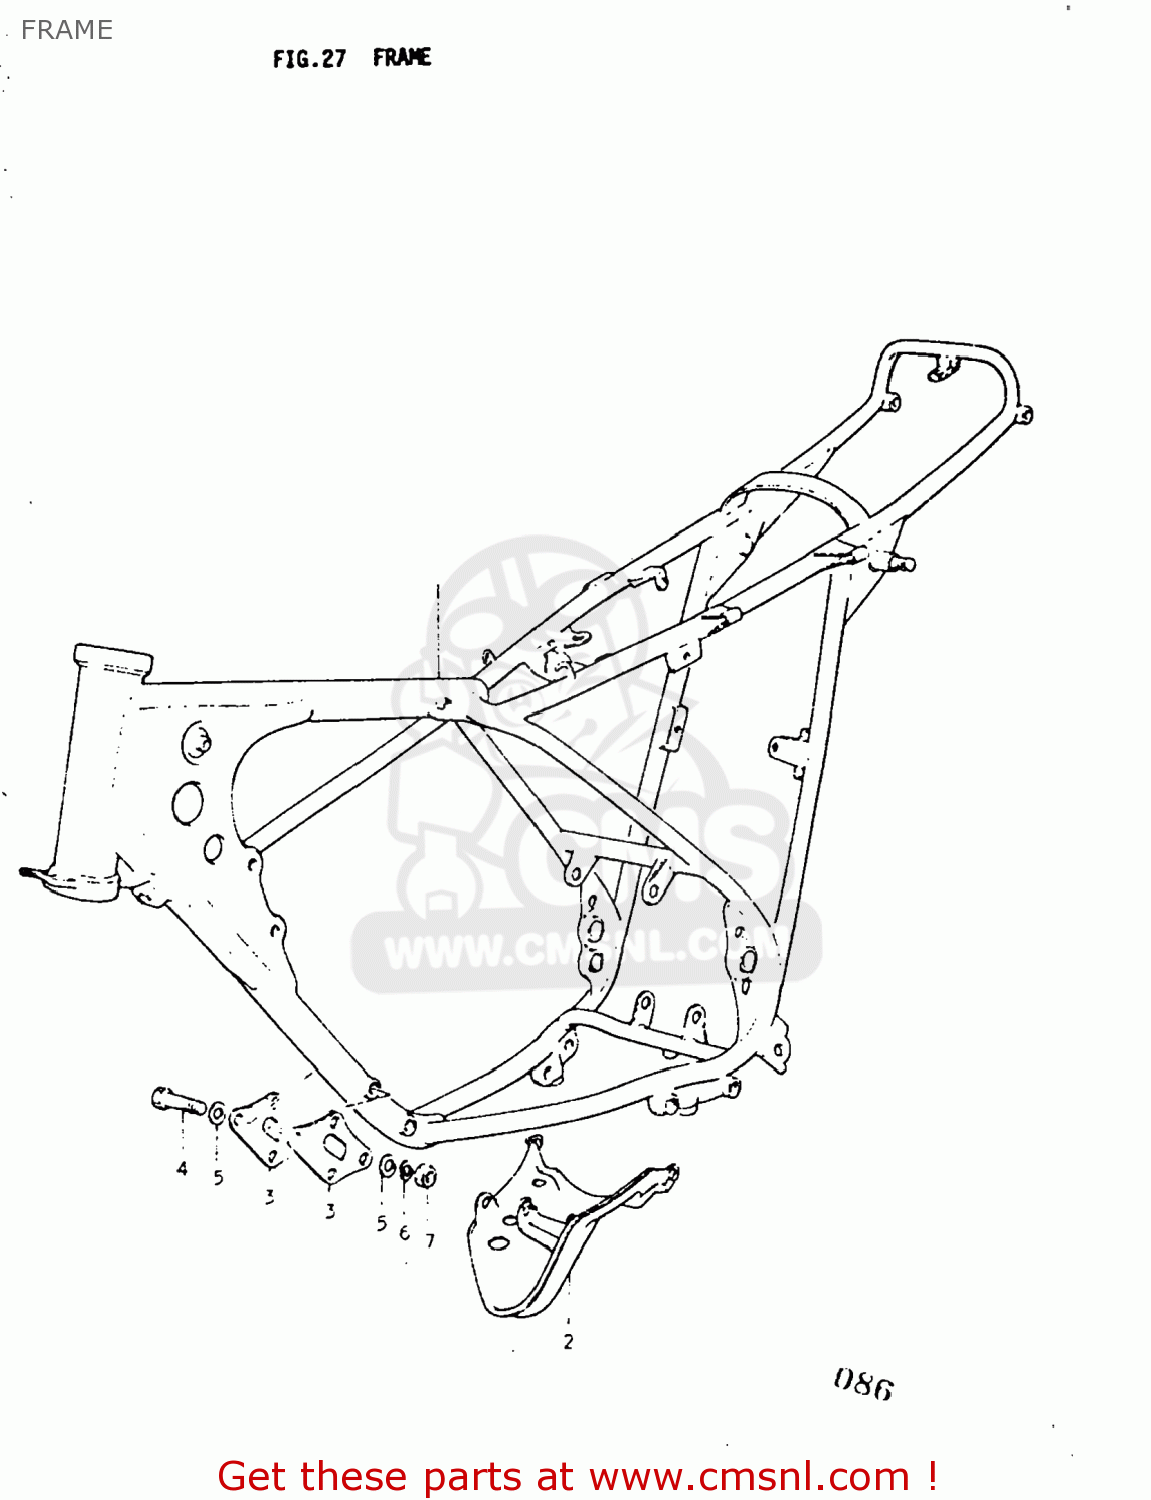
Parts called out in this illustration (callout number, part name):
1	FRAME
2	GROMMET
3	PLATE,ENGINE MOUNTING
4	BOLT
5	WASHER
6	LOCK WASHER
7	NUT
